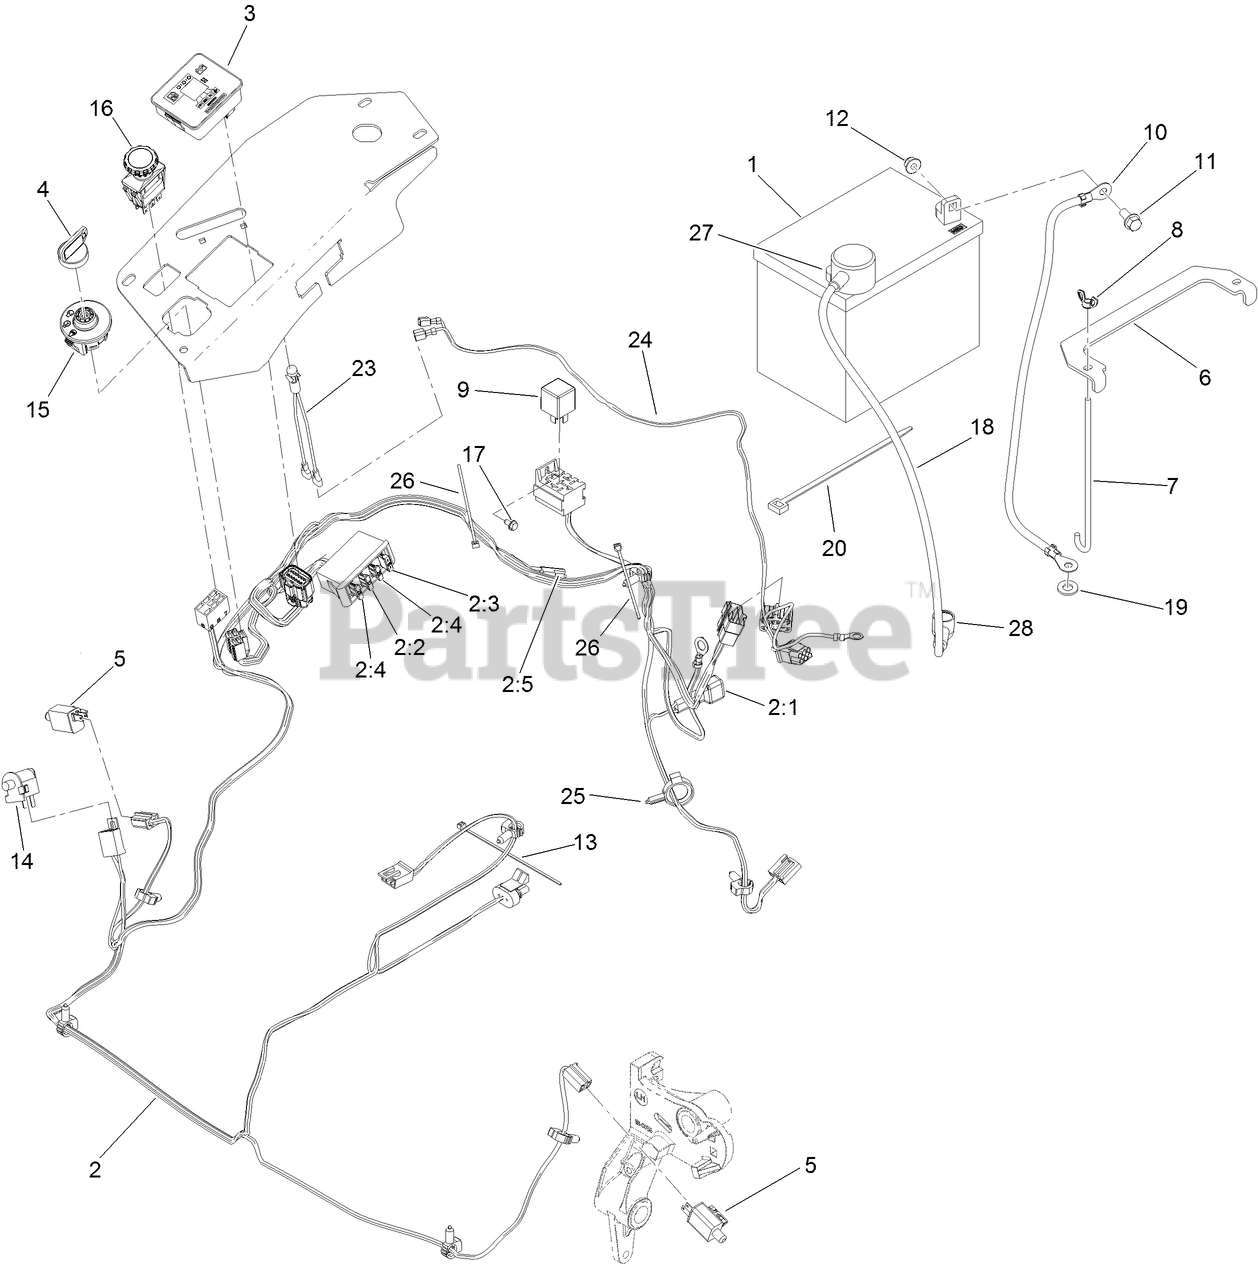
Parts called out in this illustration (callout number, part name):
1	BATTERY-DRY
2	HARNESS-WIRE, MAIN
2:2	FUSE-BLADE, 10 AMP
2:3	FUSE-BLADE, 15 AMP
2:4	FUSE-BLADE, 25 AMP
2:5	CAP-PLUG
3	FUEL/HOUR METER ASM
4	KEY-IGNITION
5	SWITCH
6	STRAP-TIE DOWN, BATTERY
7	BOLT-HOLDDOWN
8	WINGNUT
10	CABLE-BATTERY, NEGATIVE
11	SCREW-HHF
12	NUT-HF, NI
13	TIE-CABLE
14	SWITCH-BAIL
15	SWITCH-IGNITION
16	SWITCH-PTO, 10 AMP
17	SCREW-HWH
18	CABLE-BATTERY, POSITIVE
19	WASHER-FLAT
20	TIE-PLASTIC
23	INDICATOR-LED, RED
24	HARNESS-LIGHT, INDICATOR
25	CLAMP-HOSE
26	TIE-CABLE
27	INSULATOR-BATTERY
28	INSULATOR-SOLENOID
